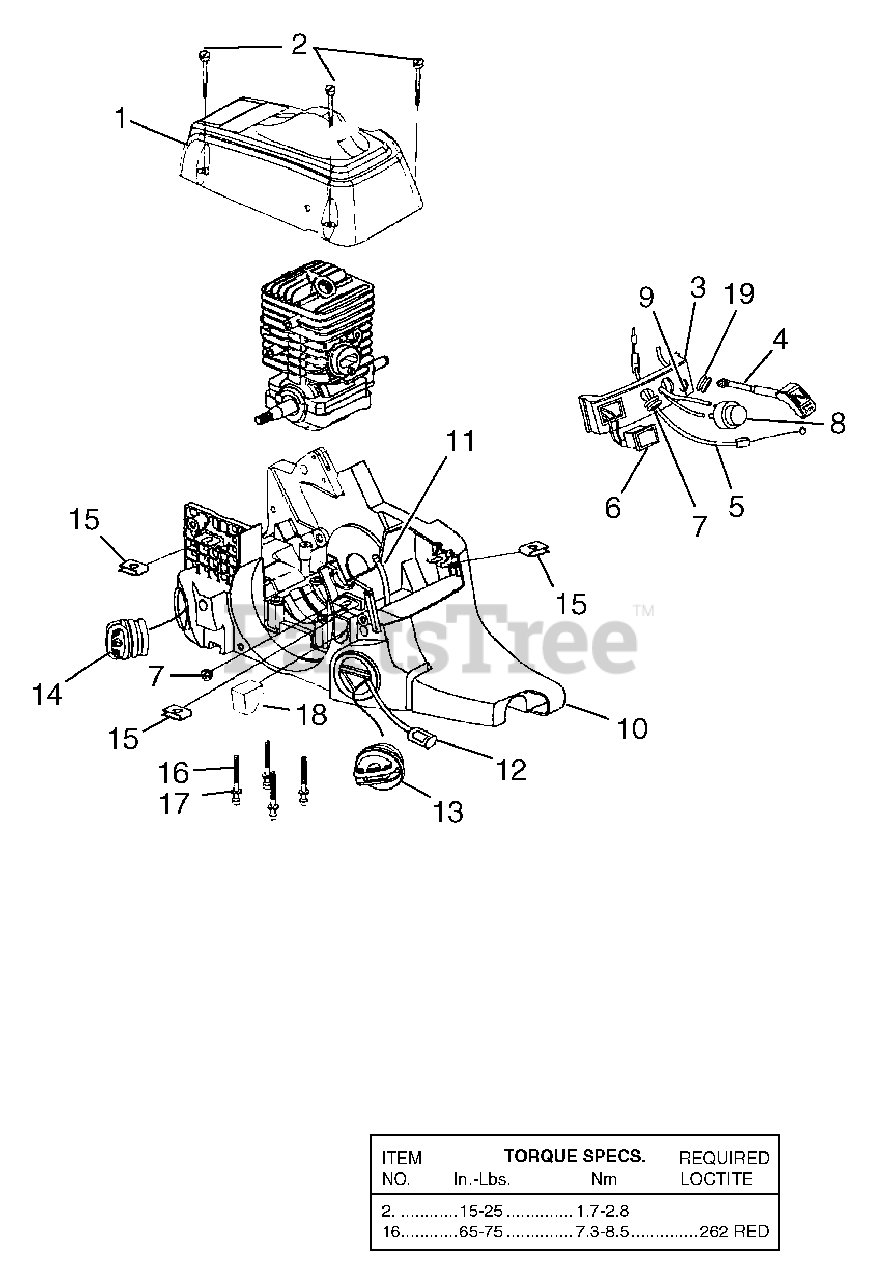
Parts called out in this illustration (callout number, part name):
1	CYLINDER COVER
2	SCREW-SLOTTED PAN HEAD
3	CONTROL PANEL
4	CHOKE ROD
5	THROTTLE CABLE
6	ROCKER SWITCH
7	SPLIT GROMMET
8	PRIMER BULB
9	RUBBER TUBING (5-1/2 in.)
11	RUBBER TUBING (8-1/2 in.)
12	FUEL FILTER
13	FUEL CAP, W/RETAINER
14	OIL CAP, W/RETAINER
15	SPEED NUT (U-TYPE)
16	SCREW, (10-24 x 2 in.)
17	WASHER
18	PRE FILTER
19	GROMMET
